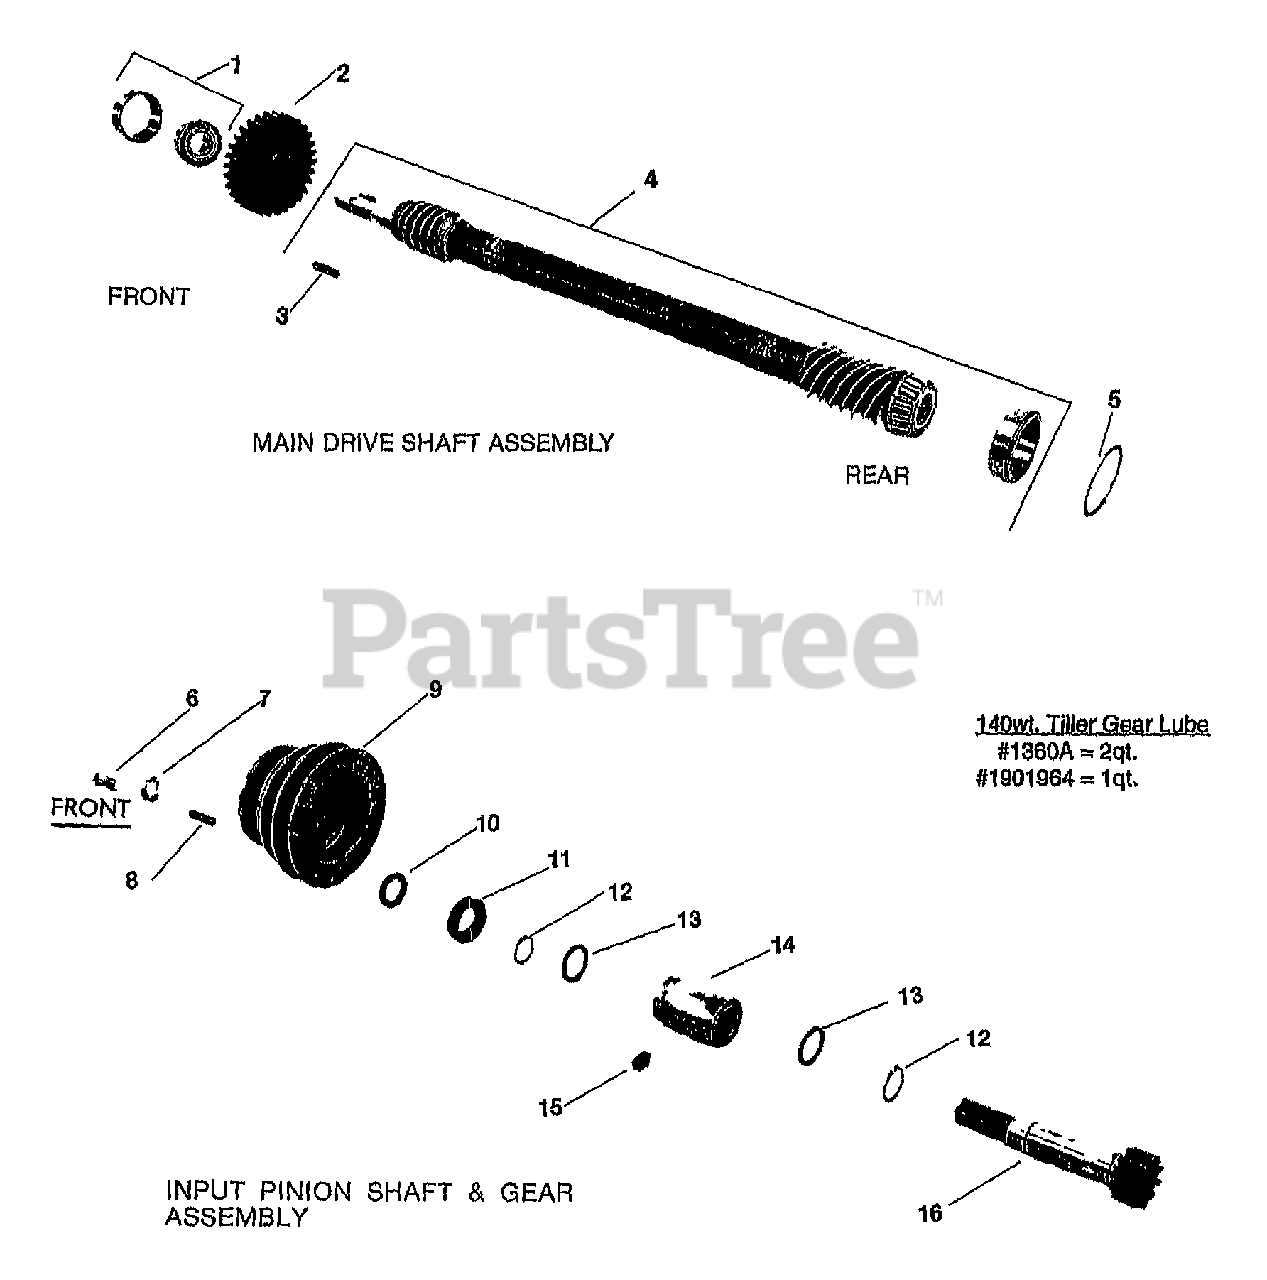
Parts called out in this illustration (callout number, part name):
1	KIT-BRG CONE&RACE-DRIVESHAFT
2	GEAR-SPUR 30 TEETH
3	KEY-.188 SQX1.0
4	KIT-DRIVESHAFT
5	SHIM-1.75X1.5X.01
5	SHIM-1.75X1.5X.03
5	SHIM-1.75X1.5X.005
6	SCR-HH 5/16-24X.75 G5 ZP
7	WASHER-.827X.331X.098 (CONCAVE SURFACE FACES PULLEY)
8	KEY-.188 SQX1.0
9	PULLEY-TRANS MACH (TWO FOR FORWARD SPEEDS; ONE FOR REVERSE SPEED)
10	WASHER # .875 X .65 X .06
11	SEAL-PINION SHAFT PT/85030/00
12	RING-RETAIN EXT .707 ID
13	WASHER-1.022X.752X .059
14	BUSHING-1.24X.75X1.8 GRVD
15	SCR-SS 5/16-18X.375
16	PINION W/GEAR&SNAP RING (HARDENED TEETH)
